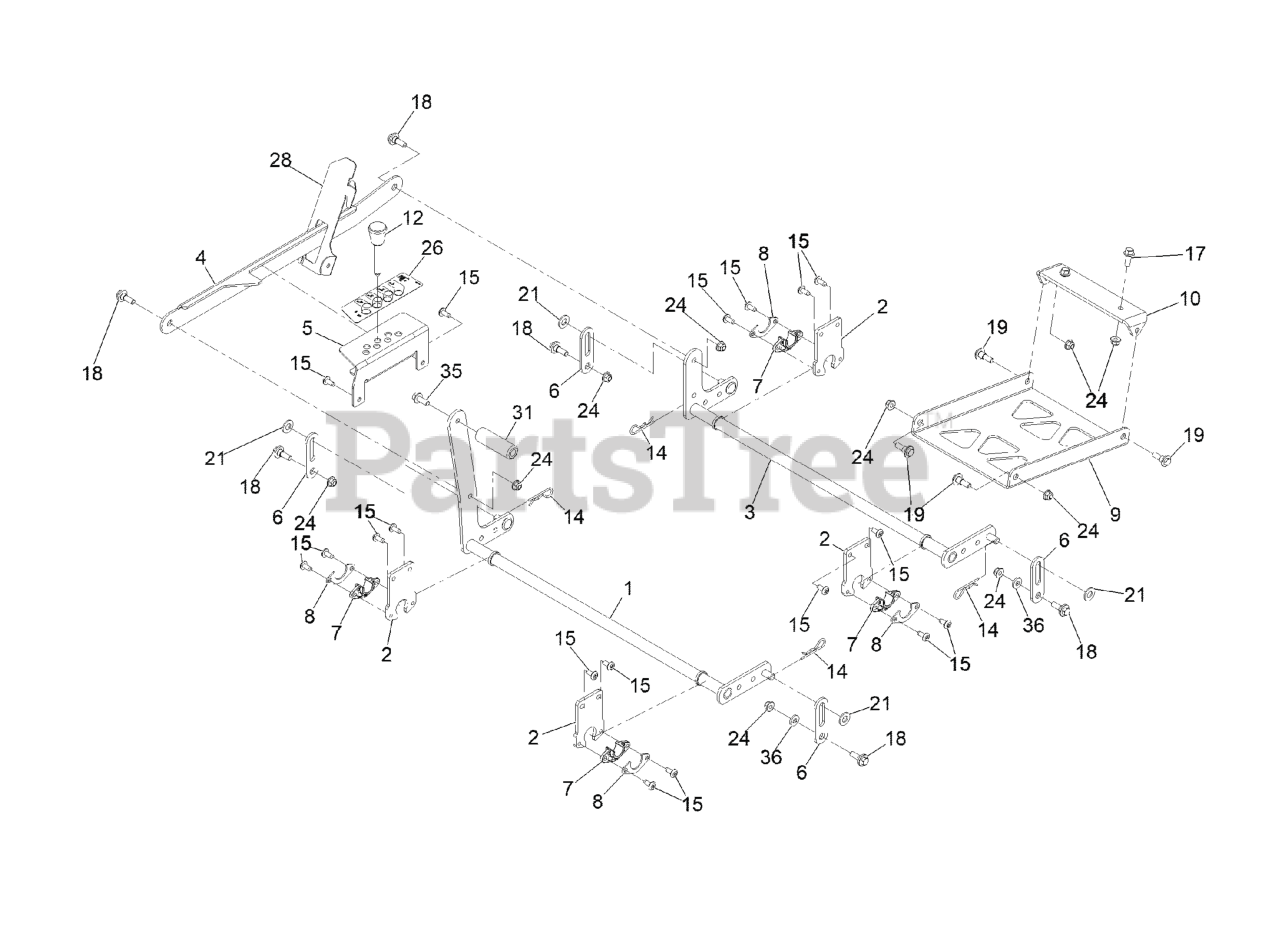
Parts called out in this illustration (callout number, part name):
1	PIVOT FRONT ASM
2	SUPPORT-CROSS, SHAFT
3	REAR PIVOT ASM
5	BRACKET-HOC
6	LINK-DECKLIFT
7	BEARING-FLANGE
8	GUSSET-DECK LIFT
9	PAN-DECK PIVOT
10	MOUNT - PAN
12	HOC PIN ASM
14	PIN-COTTER
17	SCREW-HHF 3/8-16 X 1
18	SCREW-SHOULDER
19	SCREW-SHOULDER, HHF
21	WASHER-FLAT
24	NUT-HF, NI
26	DECAL-HOC
28	BRACKET-HOC
31	PEDAL-FOOT LIFT
35	SCREW-HHF
